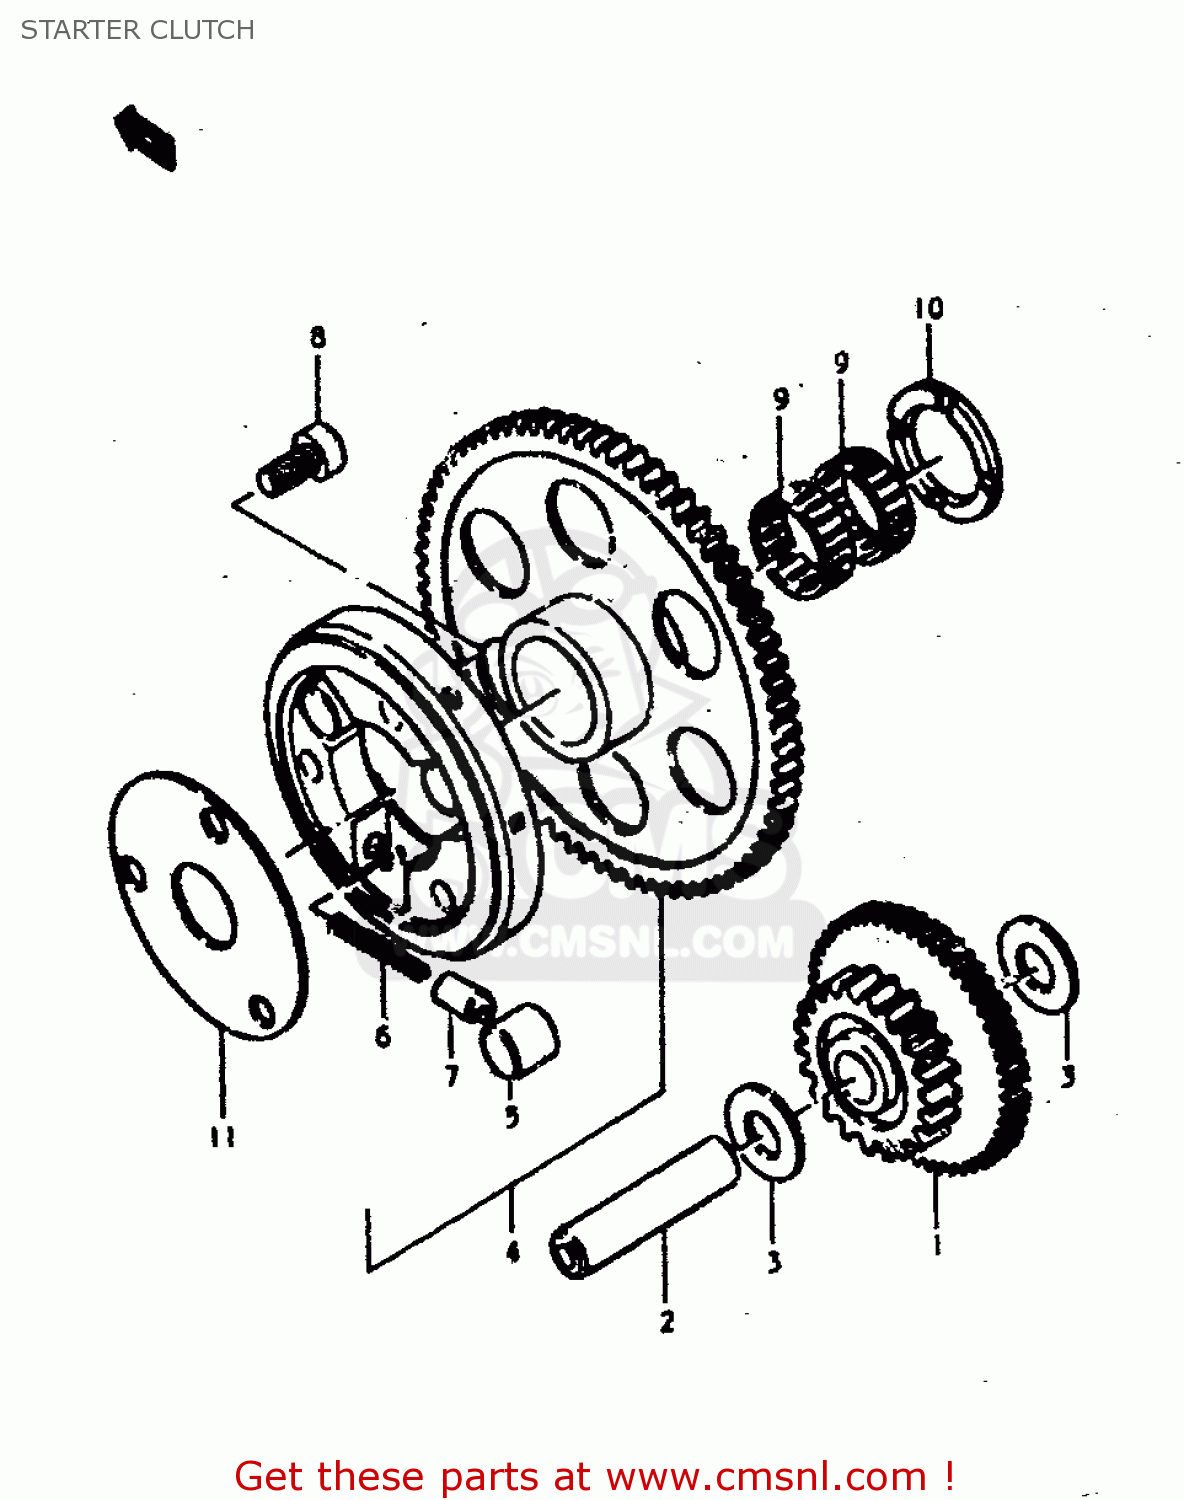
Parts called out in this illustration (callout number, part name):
1	GEAR,STARTER IDLER
2	PIN(7.4X13X56)
3	WASHER(13.3X25X0.85)
4	CLUTCH SET,STARTER
5	ROLLER(15X13)
6	SPRING
7	PIECE,PUSH
8	BOLT
9	BEARING(25X29X9.9)
10	WASHER(25X38X2.5)
11	SHIM,STARTER CLUTCH HUB
